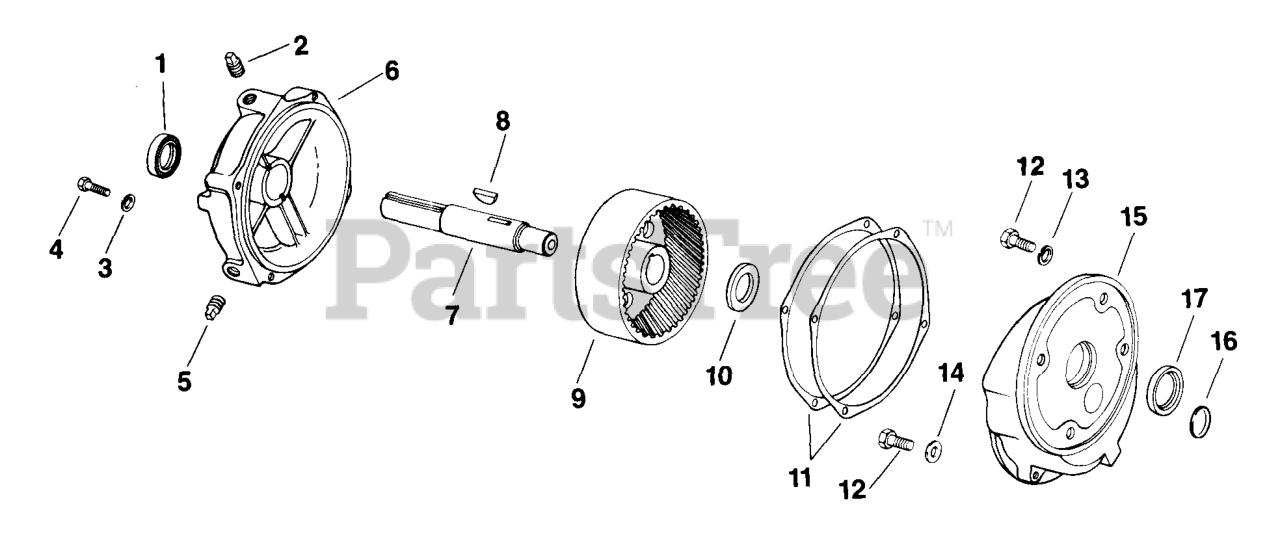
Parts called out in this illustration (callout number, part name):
3	WASHER, SPRING LOCK 5/16"
4	SCREW,CAP HD 5/16-18x2"
5	PLUG,PIPE 1/4 NPTF SQUARE HD USE 25 139 53-S
7	SHAFT - (#DSC)
8	KEY, 3/16" X 3/4"
9	GEAR - DISCONTINUED
10	BEARING
11	GASKET - USE 234498
12	SCREW, CAP HD 3/8-16X7/8"
13	WASHER, SPRING LOCK 3/8"
15	HOUSING - DISCONTINUED
